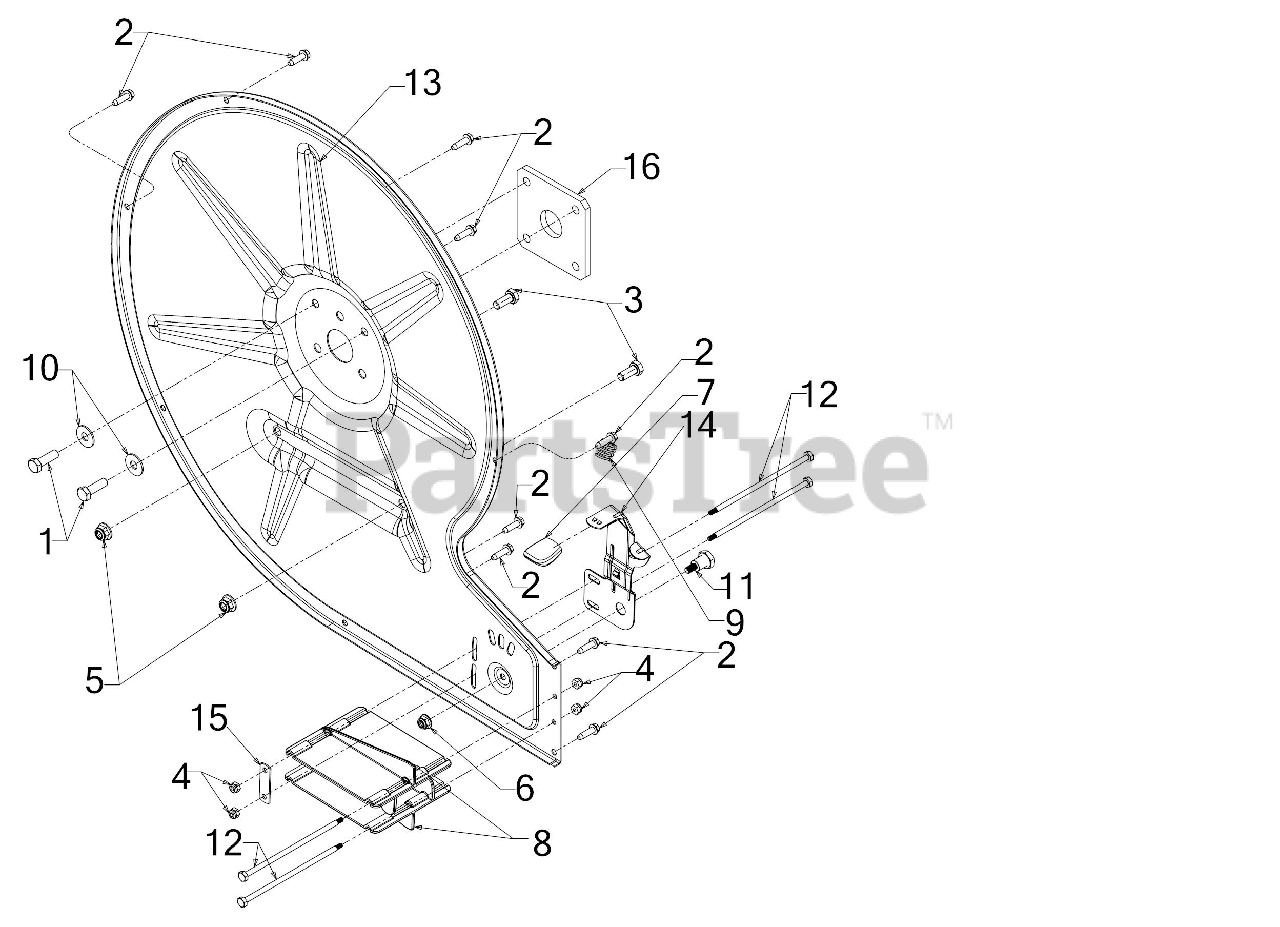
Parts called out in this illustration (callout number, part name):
1	HEX HEAD CAP SCREW 5/16-24 x 1.00 GR5
2	SCREW #12-16 .75
3	SCREW 5/16-18 x .75 GR5
5	FLANGE LOCK NUT 5/16-18
6	FLANGE LOCK NUT
7	HEIGHT ADJUSTMENT KNOB
8	LOUVER BLOWER PLATE
9	COMPRESSION SPRING
10	BELL WASHER .337 X.867 x .057
11	SHOULDER SCREW .437X.50 1/4-20
12	SHOULDER SCREW 18 x 4.8 8-32 GR5
15	GUIDE LOUVER PLATE
